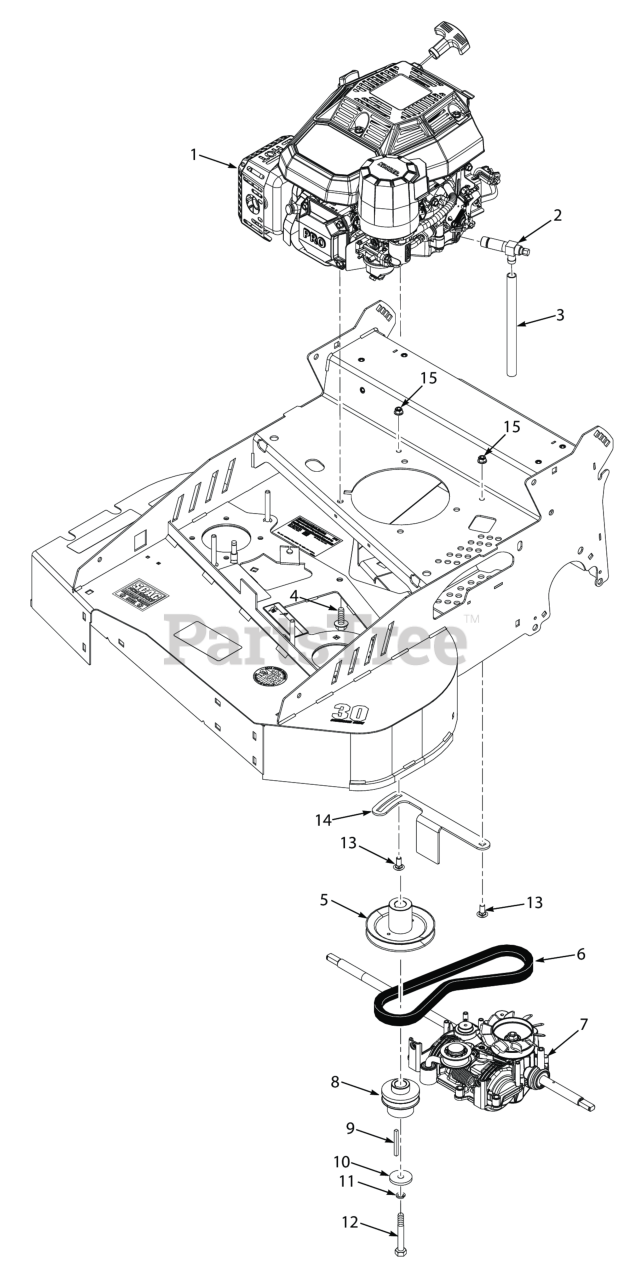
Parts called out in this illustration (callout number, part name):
1	Engine, Kohler CV224
2	Extension, Oil Drain 2.3" - Kawasaki
3	Tubing, Oil Drain (order by inch)
4	Bolt, Hex Head Self-Tap 3/8-16 x 1-1/4" (Kohler x3 - 25EFI, Kohler x4 - 29EFI)
5	Pulley, 5.20 Dia. - .875 Bore
6	Belt, Transmission
7	Transmission, MV702
8	Pulley, Transmission
9	Key, 3/16 x 3/16 x 2"
10	Flatwasher, 3/8-.406 x 1-1-1/2 x 7 Gauge
11	Lockwasher, 3/8" Spring, Kawasaki FX / FT & FT-EFI / B&S 32BV
12	Bolt, Hex Head 3/8-24 x 2" w/ Patch Lock
13	Bolt, 5/16-18 x .75 RHSN Carriage
14	Bracket, Belt Guide
15	Nut, Flange Elastic Stop 5/16-18
